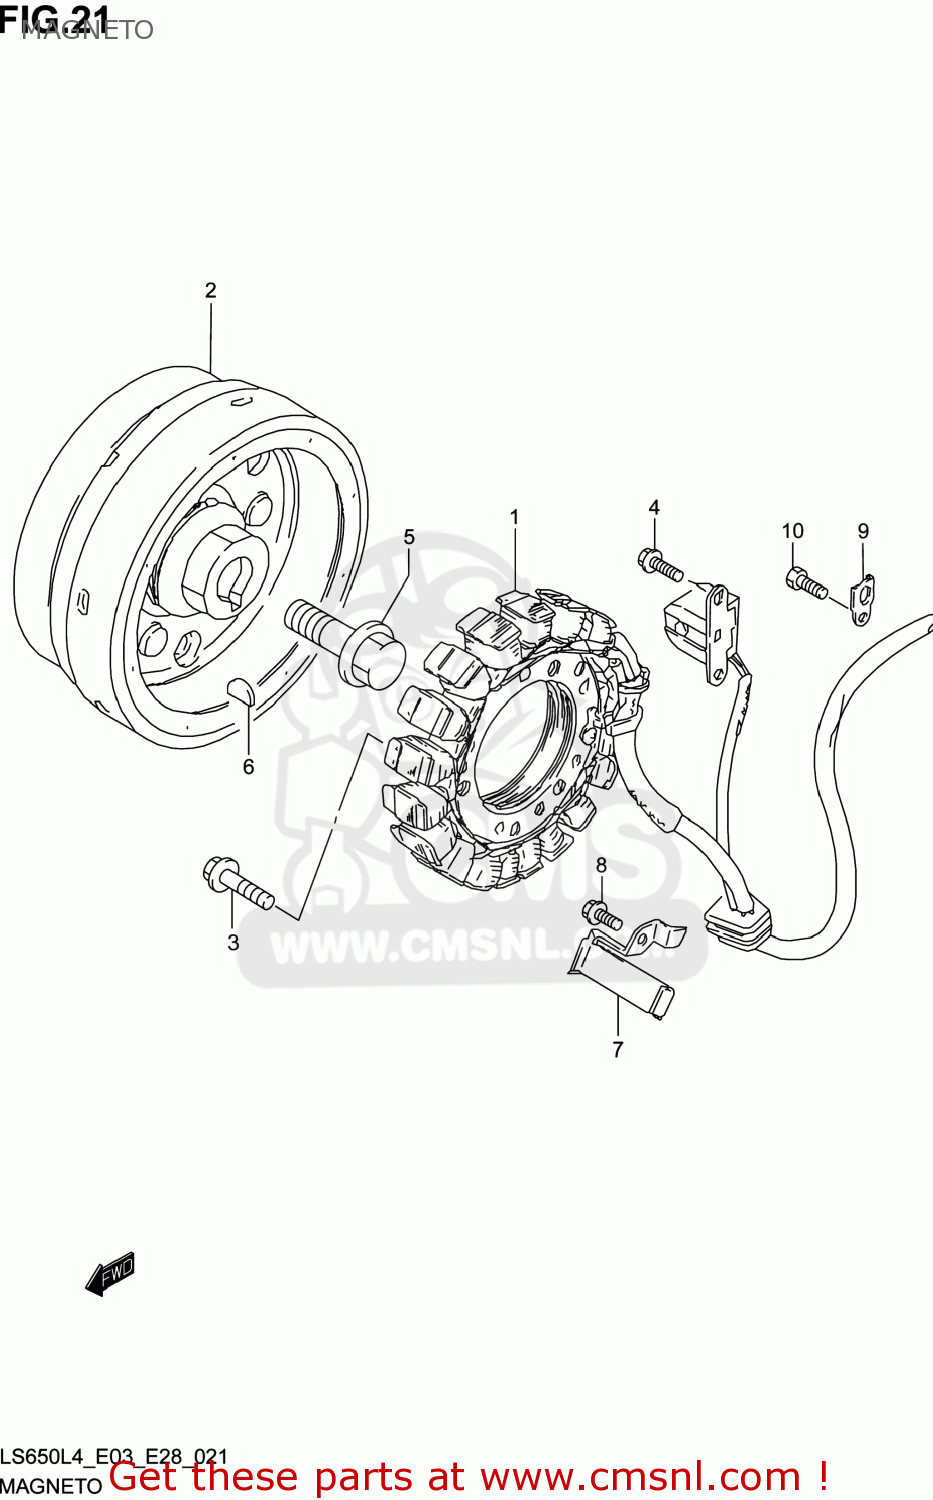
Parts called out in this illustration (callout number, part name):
1	STARTER ASSY
2	ROTOR ASSY
3	BOLT
4	BOLT
5	BOLT(14X43)
6	KEY
7	CLAMP,MAGNETO LEAD WIRE NO.1
8	BOLT
9	CLAMP,GENERATOR LEAD WIRE
10	BOLT(5X10)
